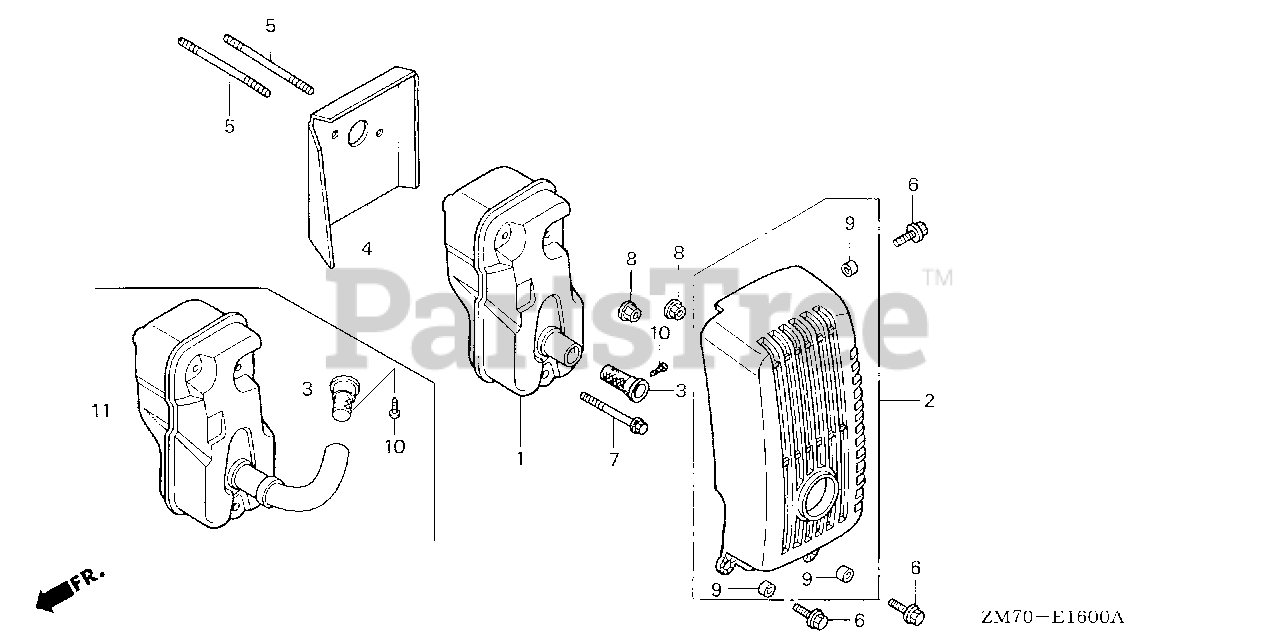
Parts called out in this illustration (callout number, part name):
1	MUFFLER
3	ARRESTER, SPARK
4	GUIDE, AIR
5	BOLT, STUD (5X55)
7	BOLT, FLANGE (5X35)
8	NUT, SELF-LOCK (5MM)
10	SCREW, TAPPING (4X8)
